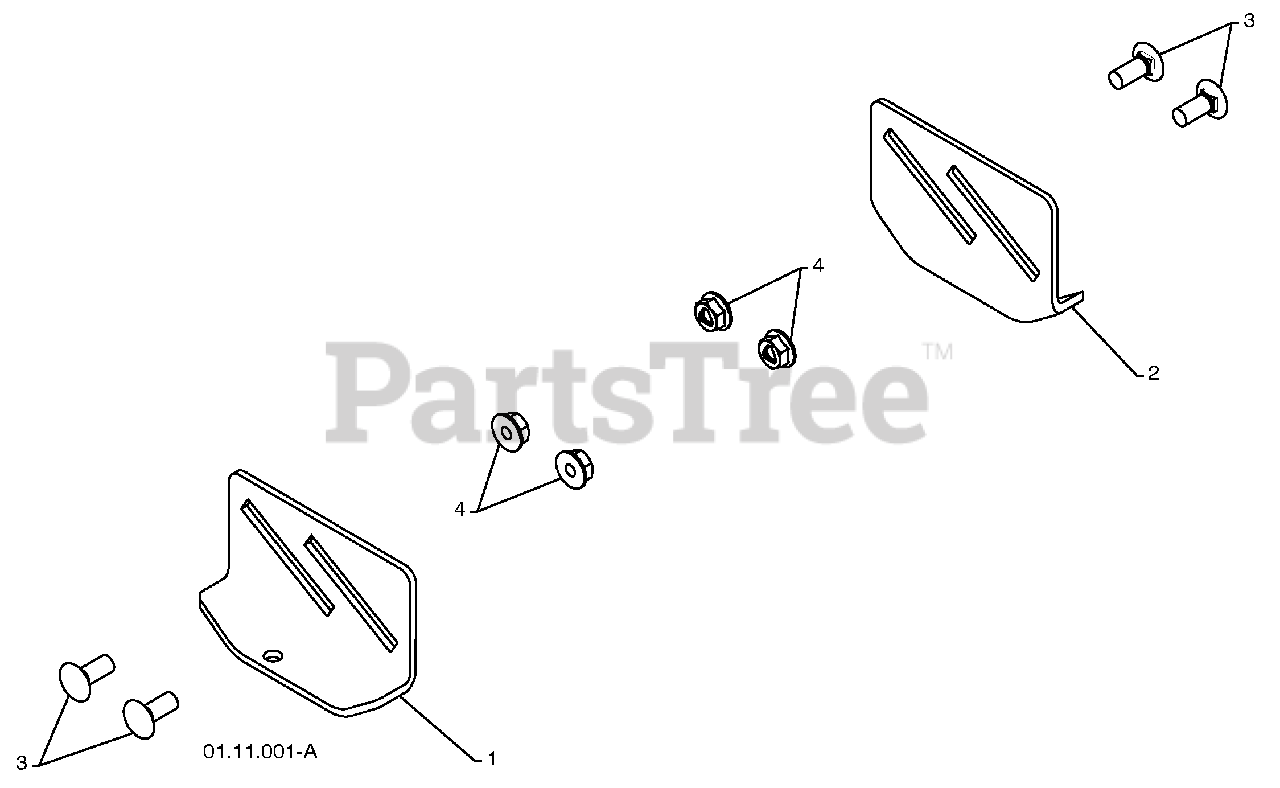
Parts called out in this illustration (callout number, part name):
1	SKID PLATE LH
2	SKID PLATE RH
3	CARRIAGE BOLT 5/16-18 X .75
4	NUT 5/16-18
